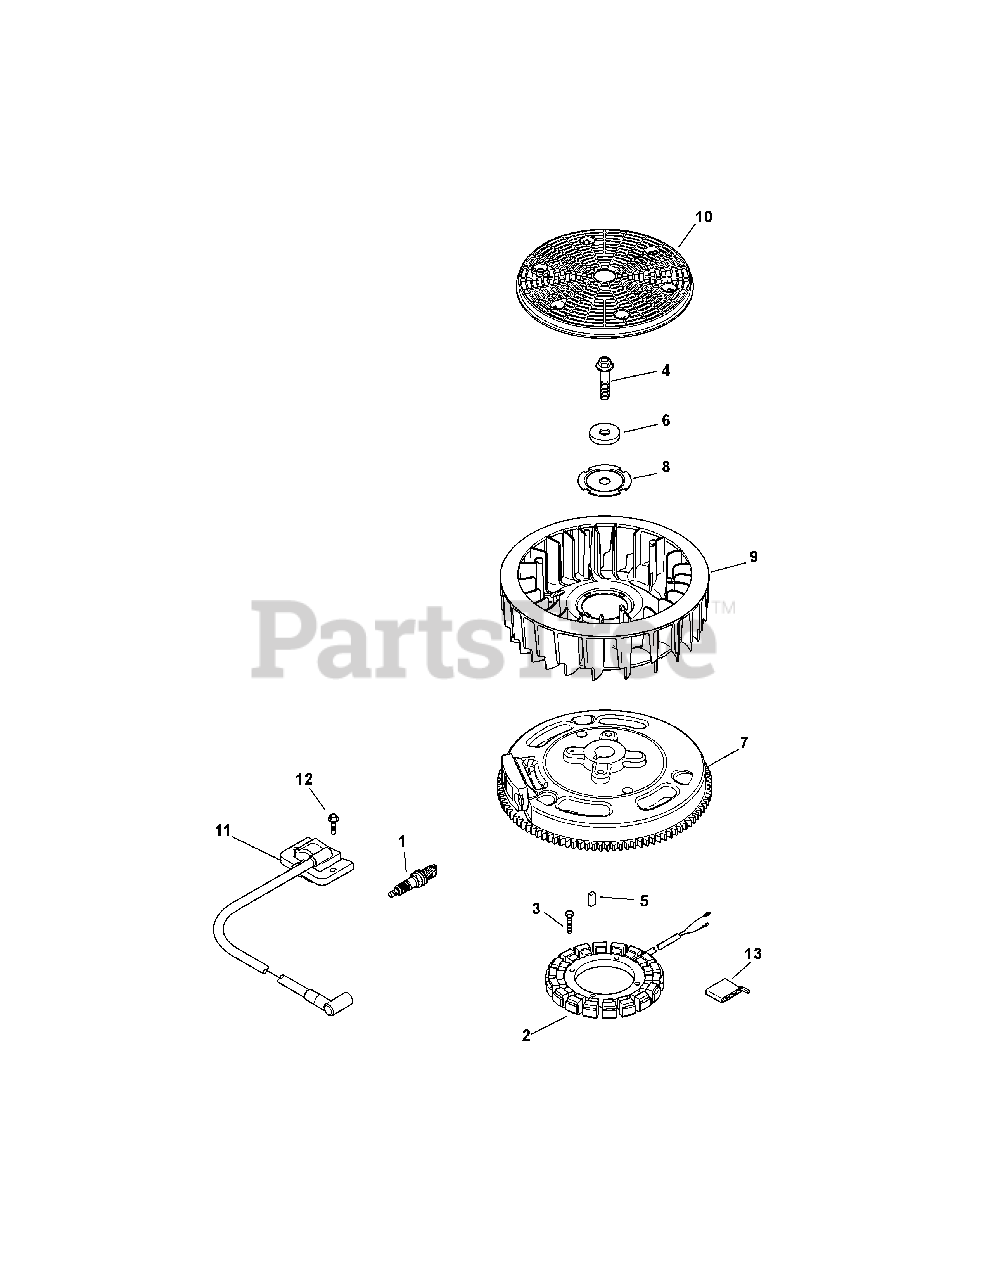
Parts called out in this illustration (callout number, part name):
1	Spark Plug
2	15 Amp Stator Kit
3	Screw, M5 x 0.8 x 25
4	Hex Flange Screw
7	Flywheel Assembly
8	Fan Mounting Plate
9	Fan
11	Module Ignition Kit
12	Screw, M5 x .8 x 20
